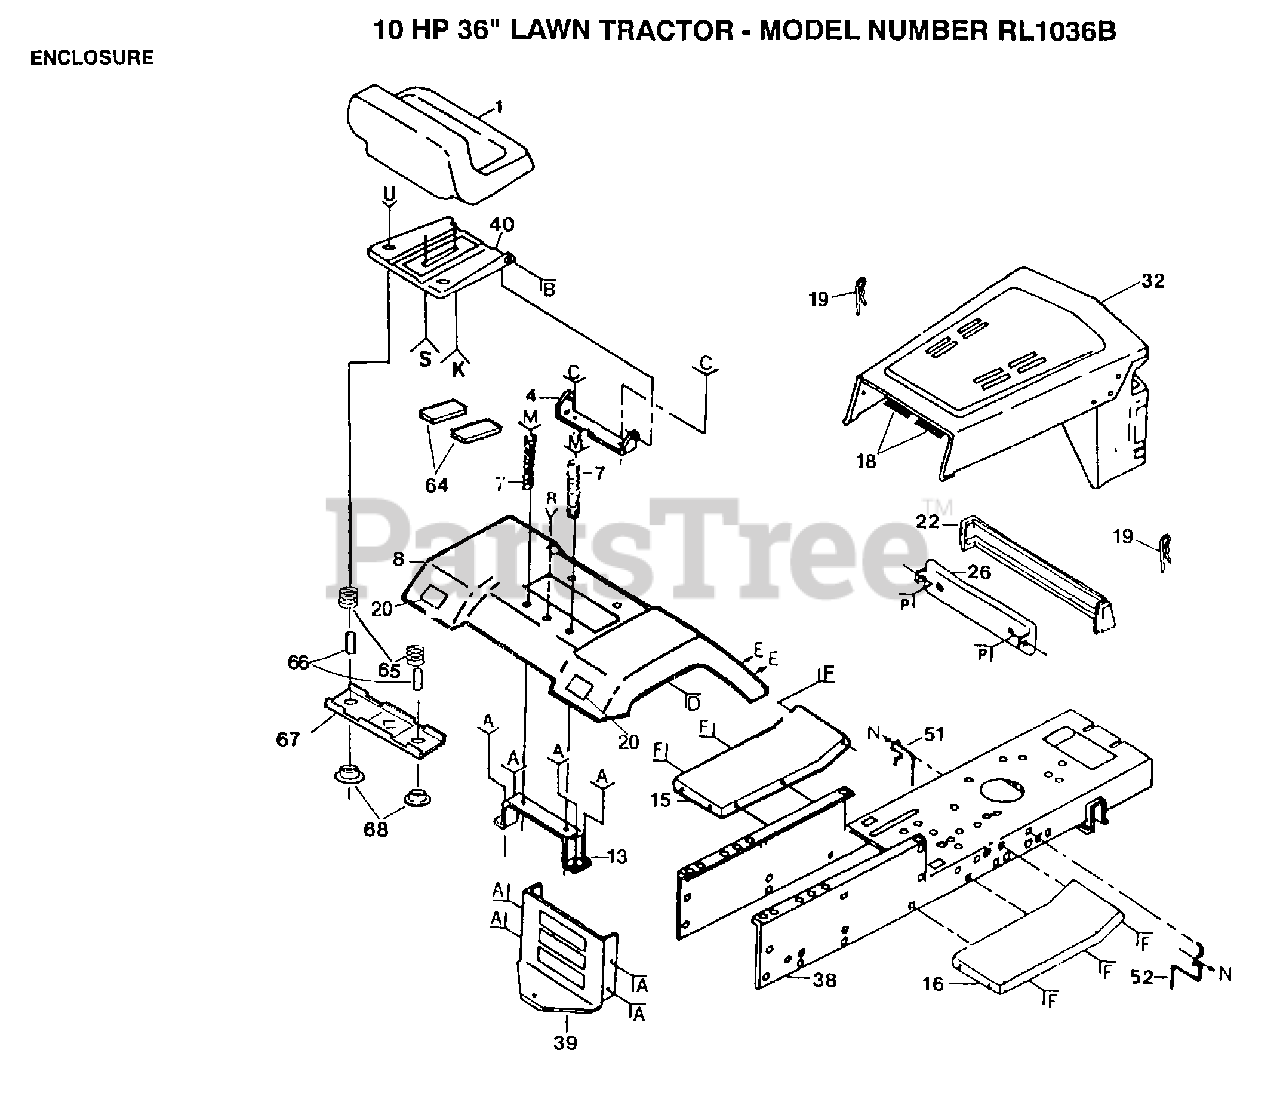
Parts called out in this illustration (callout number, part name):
2	SCREW
3	SCREW GTV
7	SPRING COMPRESSIO
9	WASHER
12	SCREW LT
14	"BOLT,SHOULDER"
15	FOOTREST LH
16	FOOTREST
17	BOLT
19	SPRING.RETAINER
20	REFLECTOR-TAIL YT
21	PAL NUT LT
24	WASHER
27	BOLT
32	HOOD&GRILL ASSY
38	CHASSIS ASS'Y
39	DRAWBAR LT/YT
47	WASHER
48	LOCKWASHER
49	WASHER
50	BOLT
51	BELT GUIDE
52	BELT GUIDE
59	WASHER
60	WASHER PM
62	BOLT
64	STRIP FORM
65	SPRING
66	SPACER SPLIT
67	BRKT SWITCH
68	BUSHING
